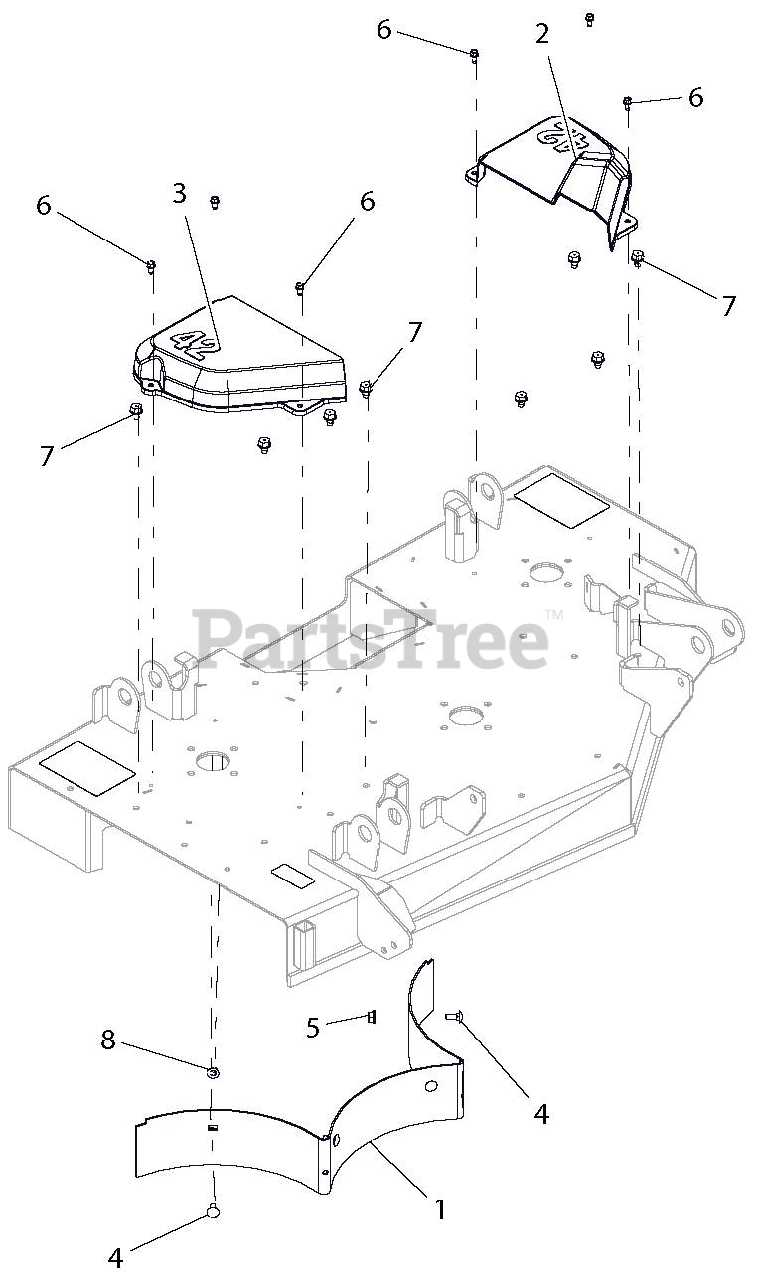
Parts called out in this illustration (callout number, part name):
1	BAFFLE, REAR 42
2	COVER, BELT 42" LH
3	COVER, BELT 42" RH
4	@BLT-RDHDSQNK .31-18X.75 G5YZ
5	@NUT-LK-TOP-FLG .38-16 YWZC
6	SCR-TAP .25-20X.50 HWH TR YWZ
7	@SCR-TAP .38-16X.50 HWH TR YWZ
8	@NUT-LK-TOP-FLG .31-18 YWZC
